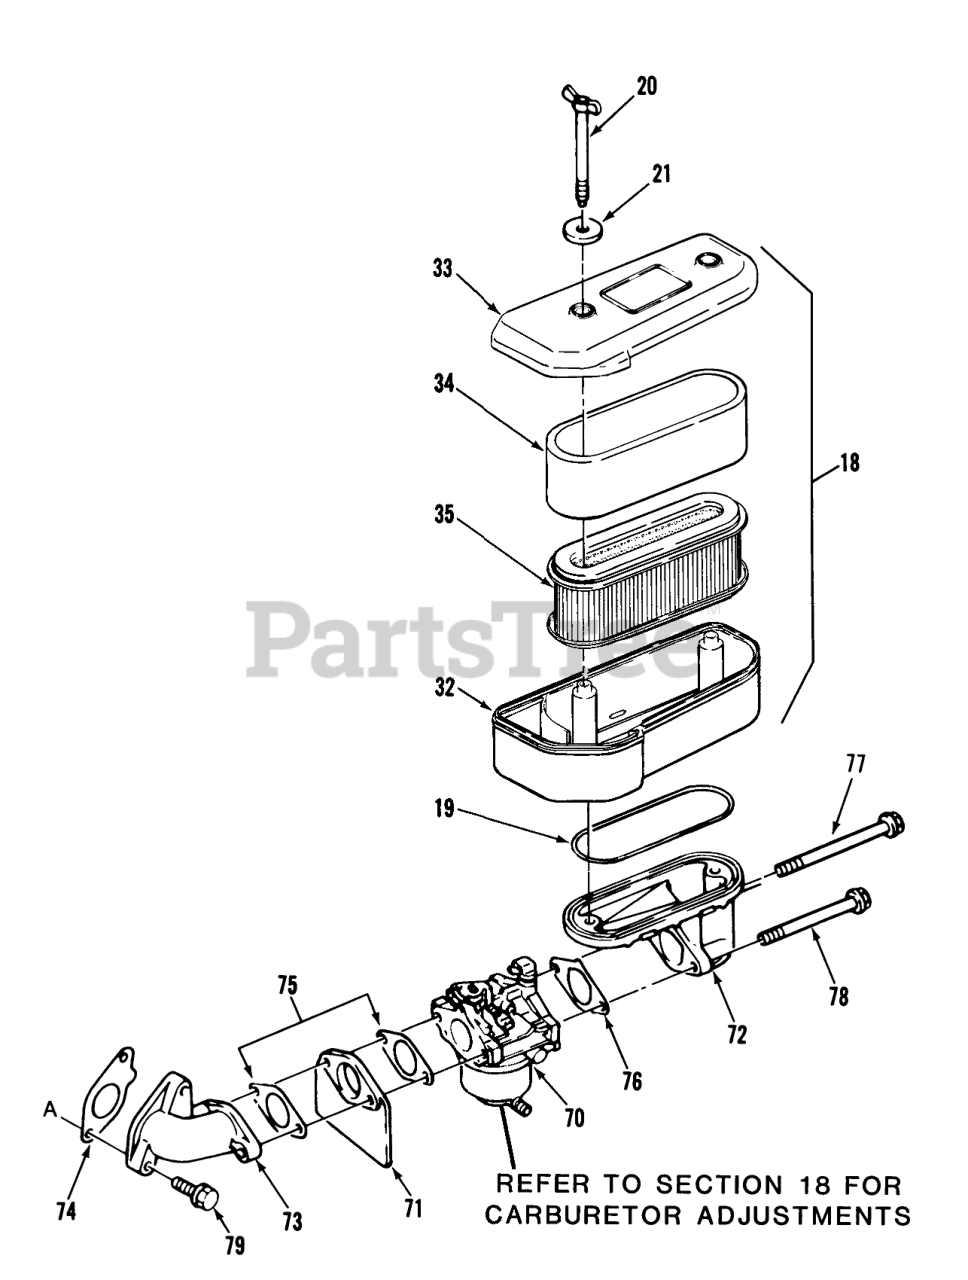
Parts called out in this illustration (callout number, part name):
18	Air Filter Assy (includes items 32, 33, 34 & 35)
19	GASKET
21	WASHER
32	CASE-AIR FILTER
33	CAP-AIR FILTER
34	ELEMENT-AIR CLEANER
35	AIR CLEANER ELEMENT
70	ASS'Y-CARBURETOR
71	INSULATOR
72	MANIFOLD INTAKE
73	MANIFOLD INTAKE
74	GASKET
75	GASKET
76	GASKET
79	BOLT, FLANGED 8X25
